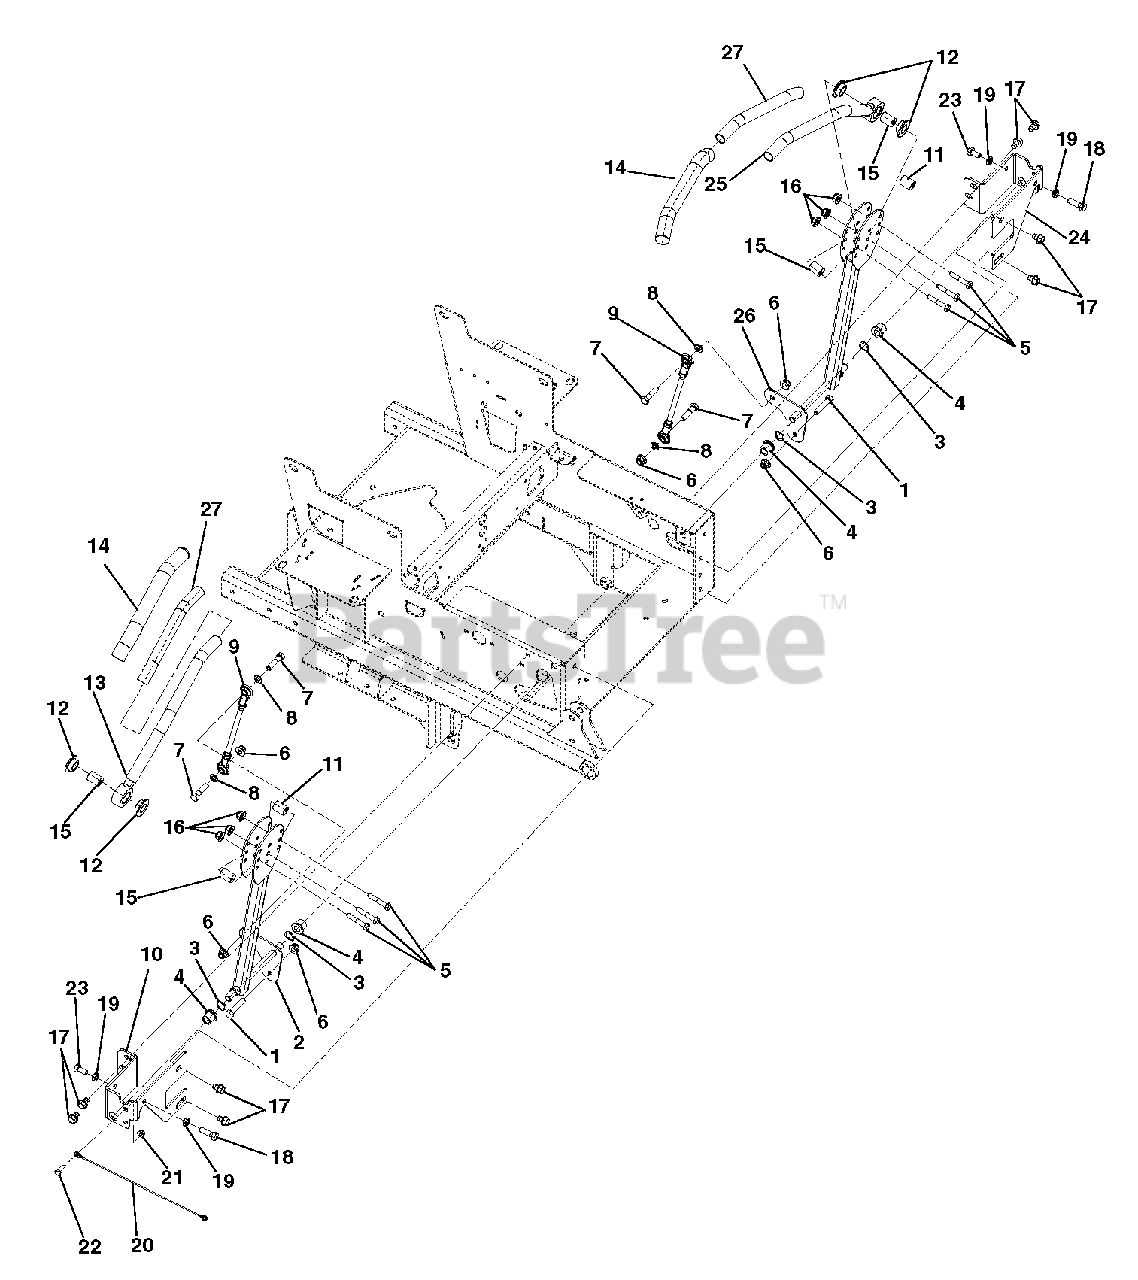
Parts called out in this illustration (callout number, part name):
1	BLT-HEX .38-16X2.0 GR5 FTD YWZ
2	WMT, RH CONTROL
3	WAVE WASHER .640X.875X.125FH
4	BSHG-FLG .515X.750X.745X1.00NY
5	@BLT-HEX .31-18X1.75 GR5 YWZC
6	@NUT-LK-NYL-FLG .38-16 YWZC
7	@BLT-HEX .38-16X1.50 GR5 YWZC
8	@WSHR-LK .38X.094 REG YWZC
9	ASM, STEERING LINKAGE
10	RH STEERING STOP BRACKET - RED
11	BSHG, ECCENTRIC .328X.750X.970
12	BSHG-FLG .762X1.48X.44 NYL
13	WLDMT, RH HANDLE
14	GRIP, HANDLEBAR 1.00X1.38X11.3
15	SPACER .328 X .76 X 1.01
16	@NUT-LK-NYL-FLG .31-18 YWZC
17	@SCR-TAP .38-16X.50 HWH TR YWZ
18	@BLT-HEX .38-16X1.25 GR5 YWZC
19	NUT-HEX-JAM .375-16 YWZC
20	CABLE, 12.0 LANYARD, NYLON
21	@NUT-LK-NYL-FLG .25-20 YWZC
22	@BLT-HEX .25-20X.75 GR5 YWZC
23	@BLT-HEX .38-16X.75 GR5 YWZC
24	LH STEERING STOP BRACKET - RED
25	HANDLE WLDMT LH
26	WMT, LH CONTROL
27	TUBE, .88ID X 1.00OD X 10.25
